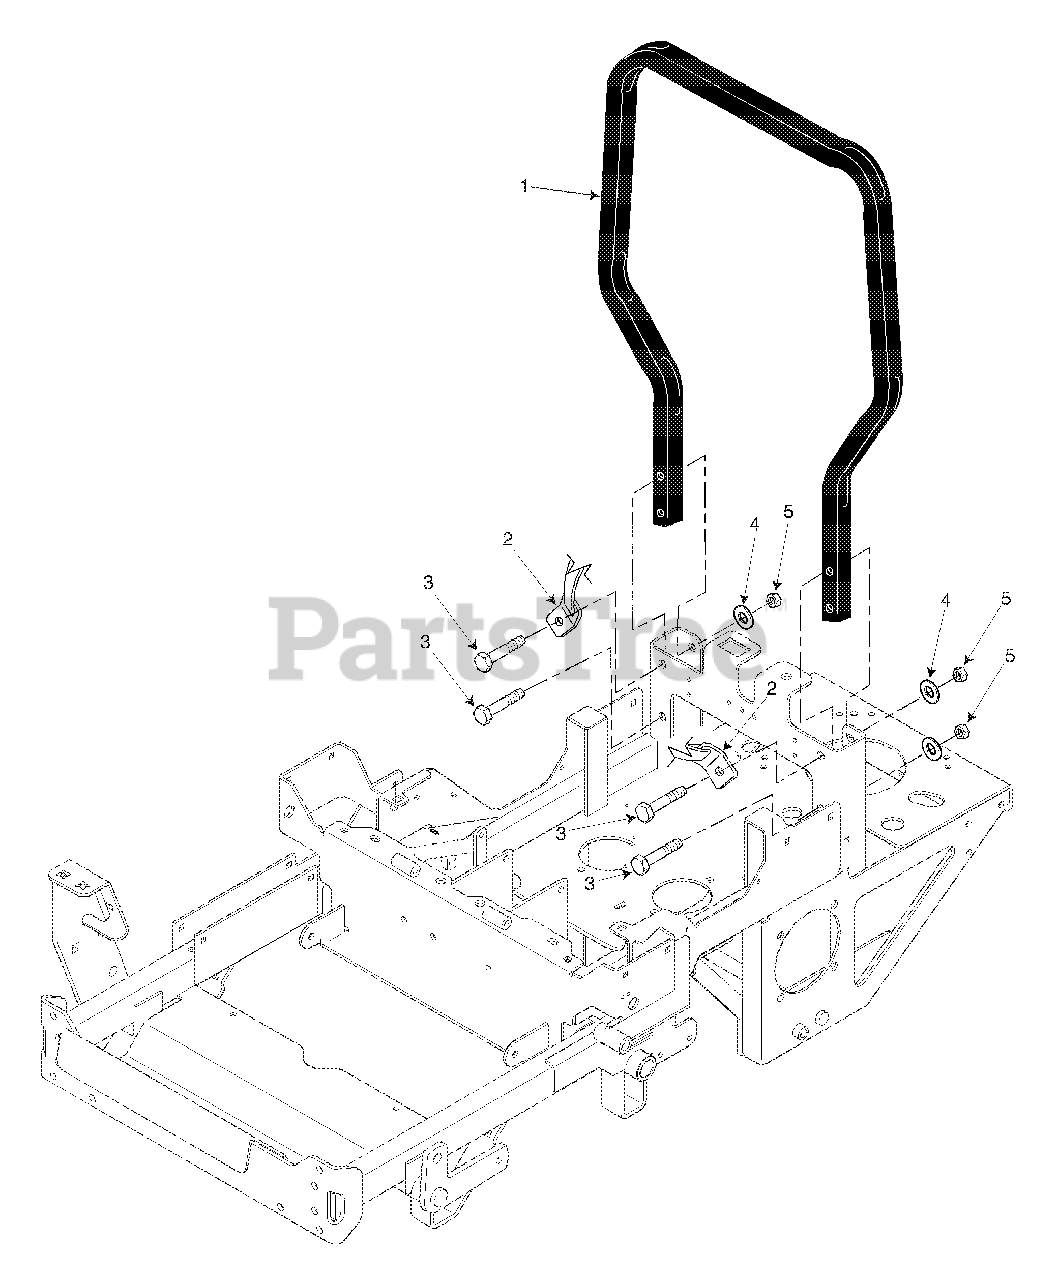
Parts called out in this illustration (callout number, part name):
1	SZC ROPS
2	Seat Belt, ROPS
3	Bolt, Hex Head 1/2-13 x 3-1/2"
4	Flatwasher, 1/2-.562 x 1.375 x .109
5	Nut, Center Lock 1/2-13
